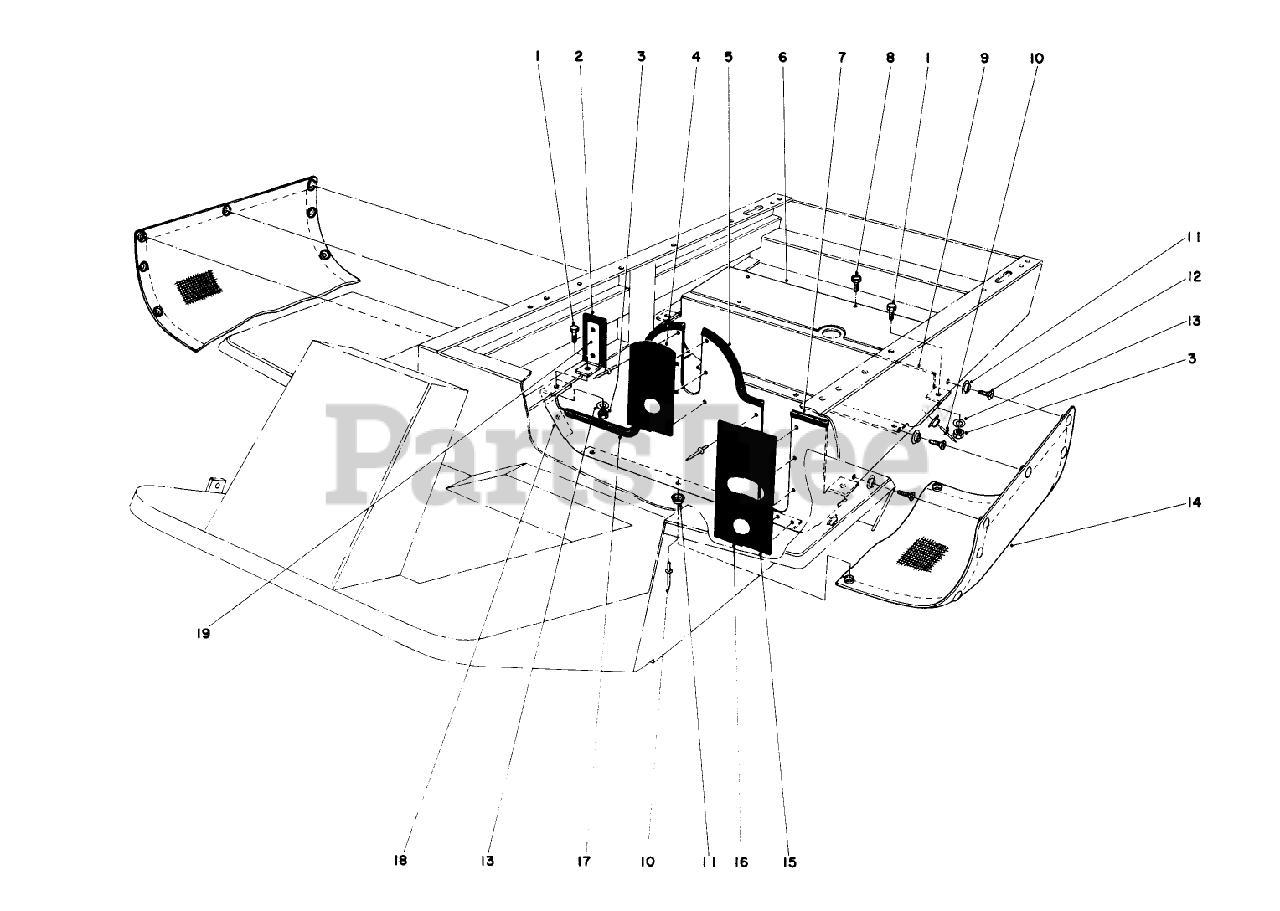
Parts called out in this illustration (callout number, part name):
1	SCREW-HH
2	CHOKE CONTROL
6	SCREW-HHFTF
7	TIE-CABLE
10	SWITCH
11	THROTTLE CONTROL
12	WASHER-FLAT
13	NUT-HEX
14	NUT-LOCK, NI
15	WASHER
16	ENGINE RUBBER MT
17	SHIM-AXLE
18	WASHER-FLAT
19	SCREW-HH
20	NUT-LOCK, NI
21	SCREW-HH
22	NUT-LOCK, NI
23	SCREW-HH
24	RUBBER MOUNT
26	SCREW-HSBH
27	NUT-LOCK, NI
28	BATT BOX FOAM
30	SCREW-HHF
31	Battery Assy.
33	NUT-HHF, WHIZ
35	NUT-JAM
36	HOUR METER
37	BRACKET
38	WASHER-LOCK, INT
39	NON SKID (TUNNEL)
40	SCREW-HH
41	SCREW-HH
43	NON-SKID-FLOOR
45	WASHER-LOCK
46	FRAME ASM
47	SCREW-HH
50	SCREW-HWH
51	NUT-HEX
52	NUT-HEX
53	WASHER-LOCK
54	WASHER-FLAT
55	MTG CLAMP F/W GUAGE
57	SCREW-HWHTF
58	BOOT-SWITCH
59	BY-PASS DECAL
60	SWITCH & BOOT ASM
62	WASHER-LOCK
63	DECAL-OIL
